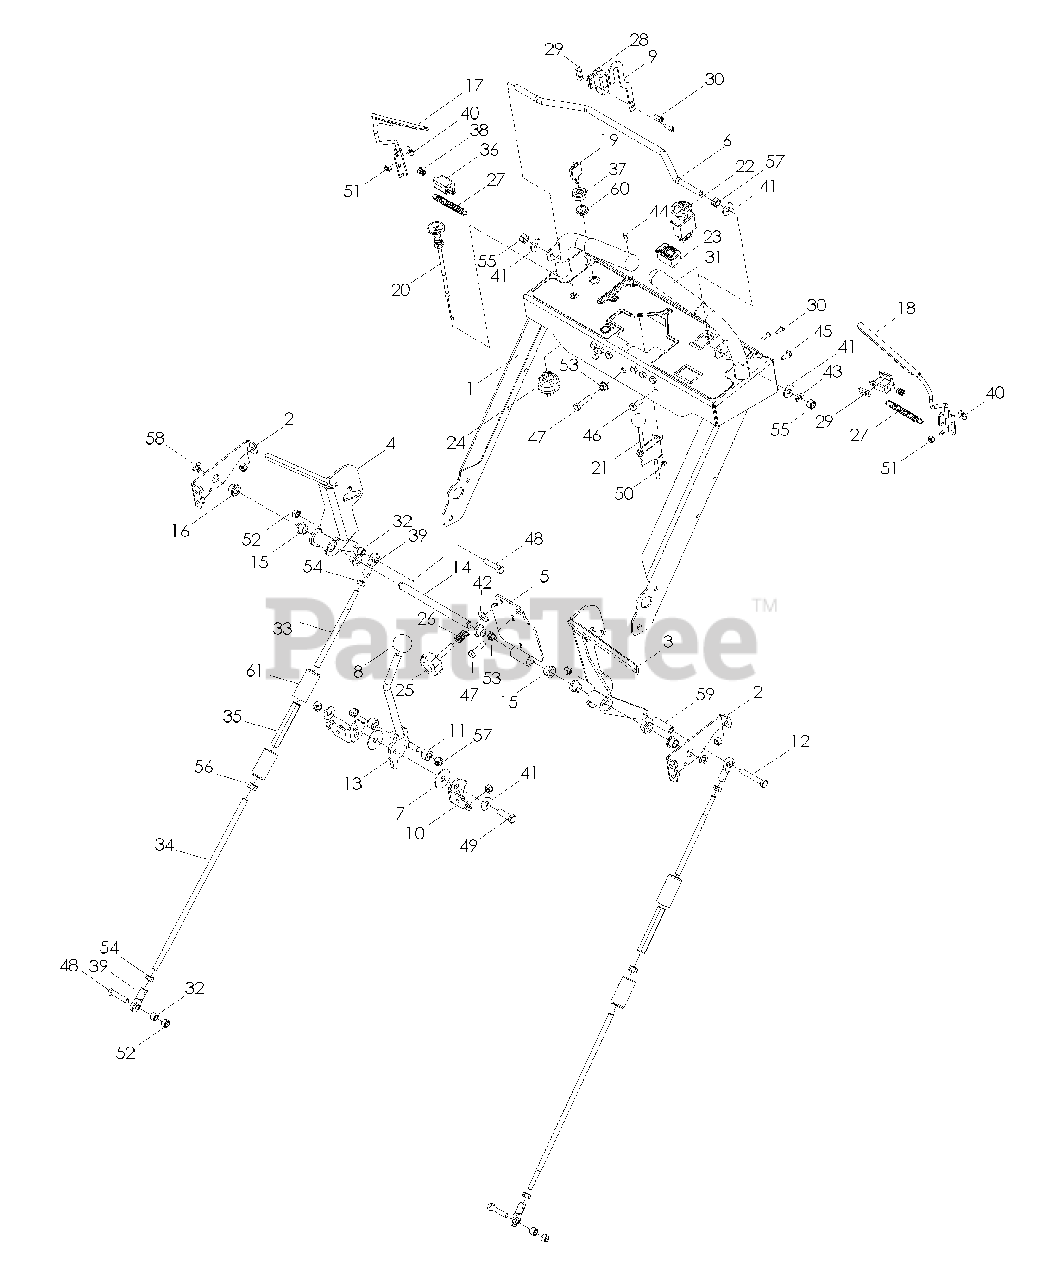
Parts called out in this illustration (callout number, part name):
1	HANDLE W/DECALS
3	DRIVE LEVER, LEFT
4	DRIVE LEVER, RIGHT
5	TRACKING PLATE
7	WASHER, FRICTION
8	KNOB, SHIFT
9	ARM, NEUTRAL
10	PLATE, FRICTION
12	HCS 5/16-18 x 2 3/4
13	LEVER, GROUND SPEED
14	SHAFT, CROSS
15	BUSHING, NYLON FLANGED
16	BUSHING, FLANGED
19	KEY, PADDED GRIP
20	CONTROL, CHOKE
21	CABLE, THROTTLE
22	SWITCH, CLUTCH
23	METER, HOUR
24	SWITCH, IGNITION
25	KNOB, ADJUSTMENT
28	SWITCH, N.C.
29	PLATE, TAPPED
30	SCREW, #10-24 x 5/8
32	SPACER, PULLEY
33	LINKAGE, SHORT
34	LINKAGE, LOWER
35	TURNBUCKLE, 3/8
36	SWITCH N.C.
37	CAP, IGNITION SWITCH NUT
38	SPRING, SWITCH
39	BALL END, RIGHT
40	WASHER 1/4
41	WASHER 3/8 FLAT
42	WASHER 5/16 STD FLT
43	LOCKWASHER 3/8
44	HCS #10-24 x 1/2
45	HCS 1/4-20 x 5/8
46	HCS 5/16-18 x 3/4
47	HCS 5/16-18 x 1 1/4
48	HCS 5/16-18 x 1 1/2
49	HCS 3/8-16 x 1 1/4
50	NUT #10-24 HEX NYLOC
51	NUT 1/4-20 HEX NYLOC
52	NUT 5/16-18 HEX NYLOC
53	NUT 5/16-18 WHIZLK
54	NUT 5/16-24
55	NUT 3/8-16 HEX NYLOC
56	NUT 3/8-24 HEX GR 2
57	NUT 3/8-16 HEX CNTRLK
58	E-RING 1/2
60	NUT, IGNITION SWITCH
